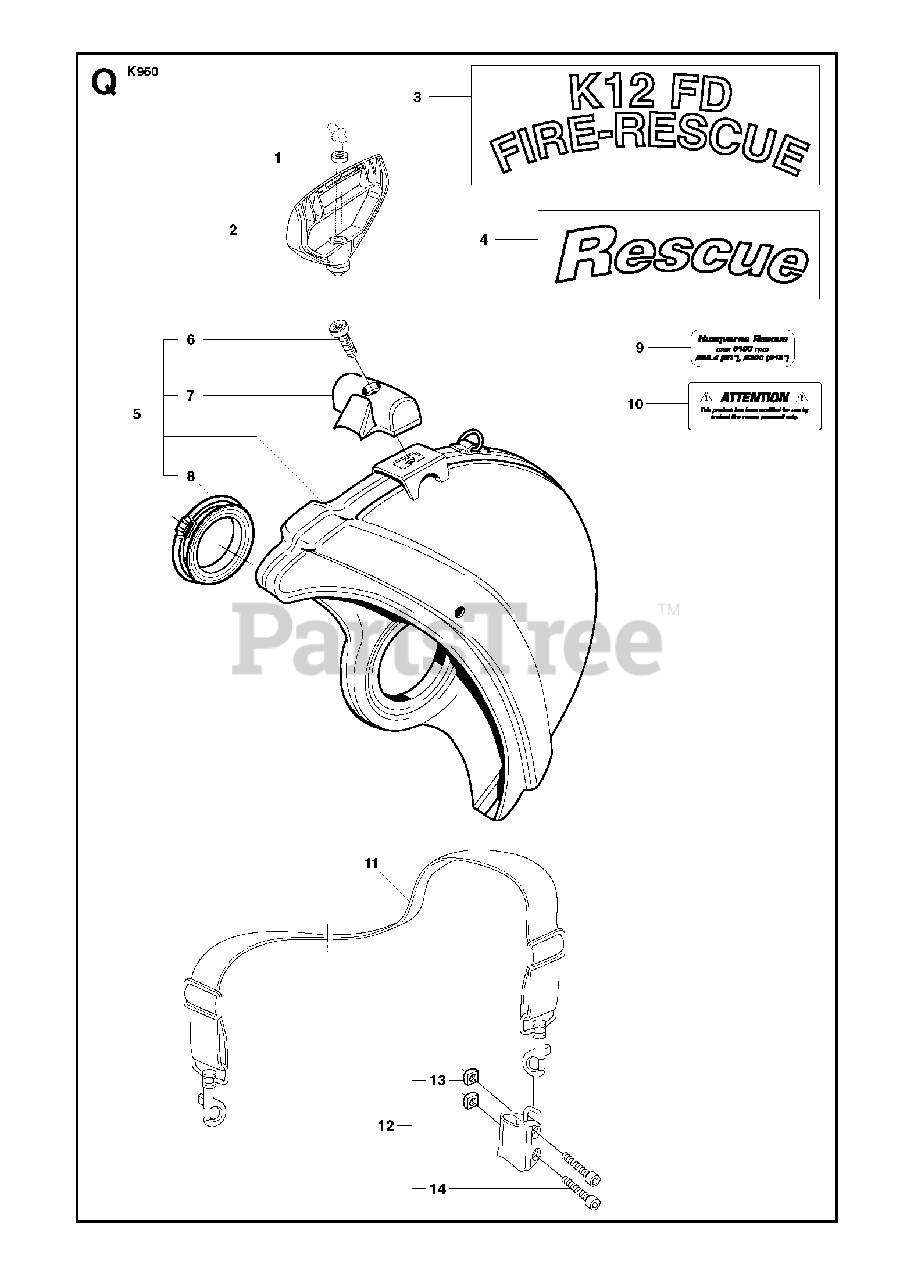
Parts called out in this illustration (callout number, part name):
2	STARTER HANDLE
5	BLADE GUARD"Rescue 14"". Incl. 6 - 8"
5	BLADE GUARD"Rescue 12"". Incl. 6 - 8"
6	SCREW ITXSCM
11	SHOULDER STRAP
12	BRACKETIncl. 13, 14
14	SCREW ITXSCM
